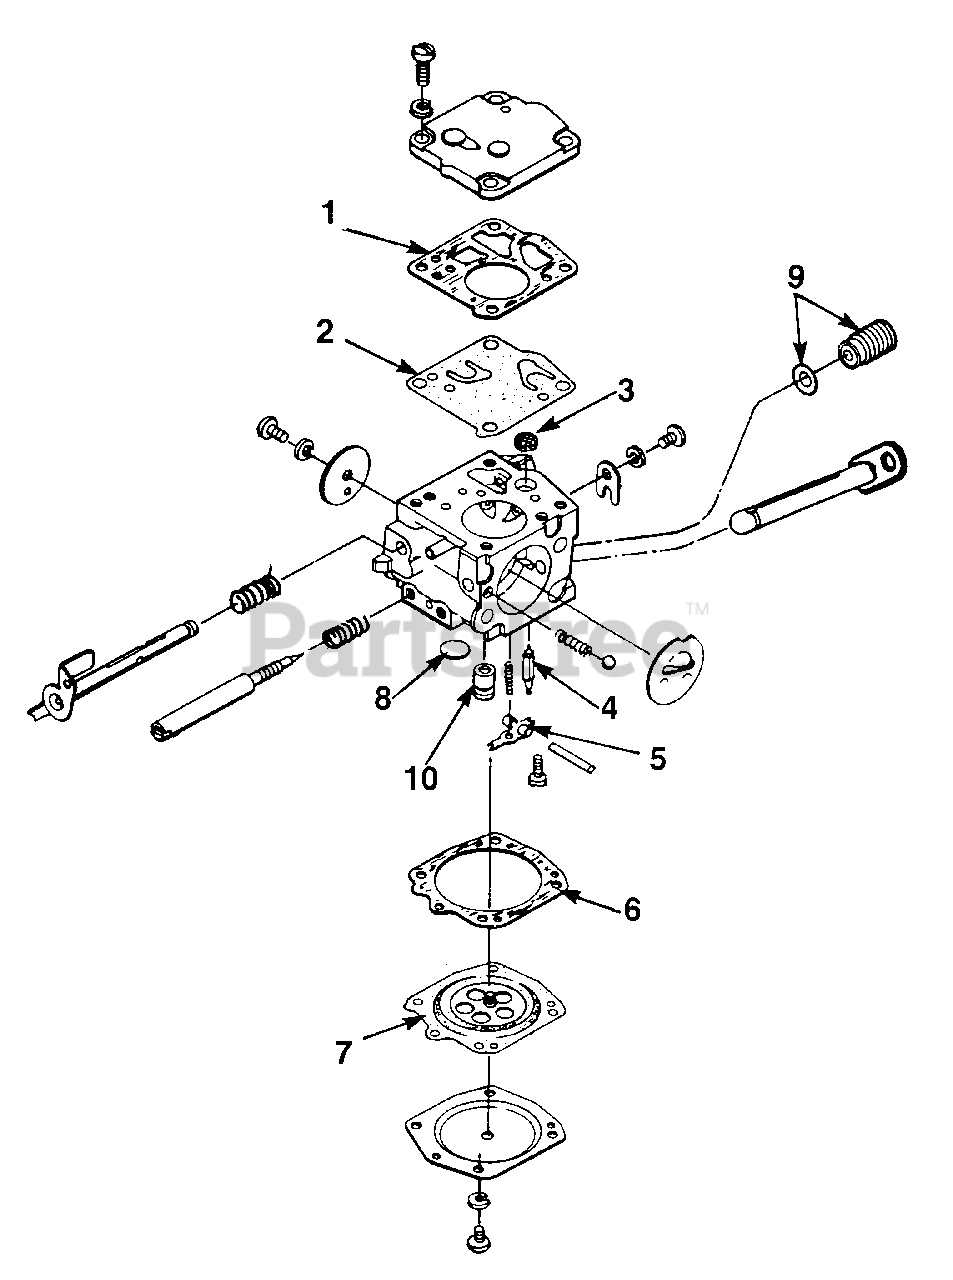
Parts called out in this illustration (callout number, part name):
1	REPAIR KIT
2	REPAIR KIT
3	REPAIR KIT
4	REPAIR KIT
5	REPAIR KIT
6	REPAIR KIT
7	REPAIR KIT
8	REPAIR KIT
9	GOVERNOR VALVE
10	CHECK VALVE
